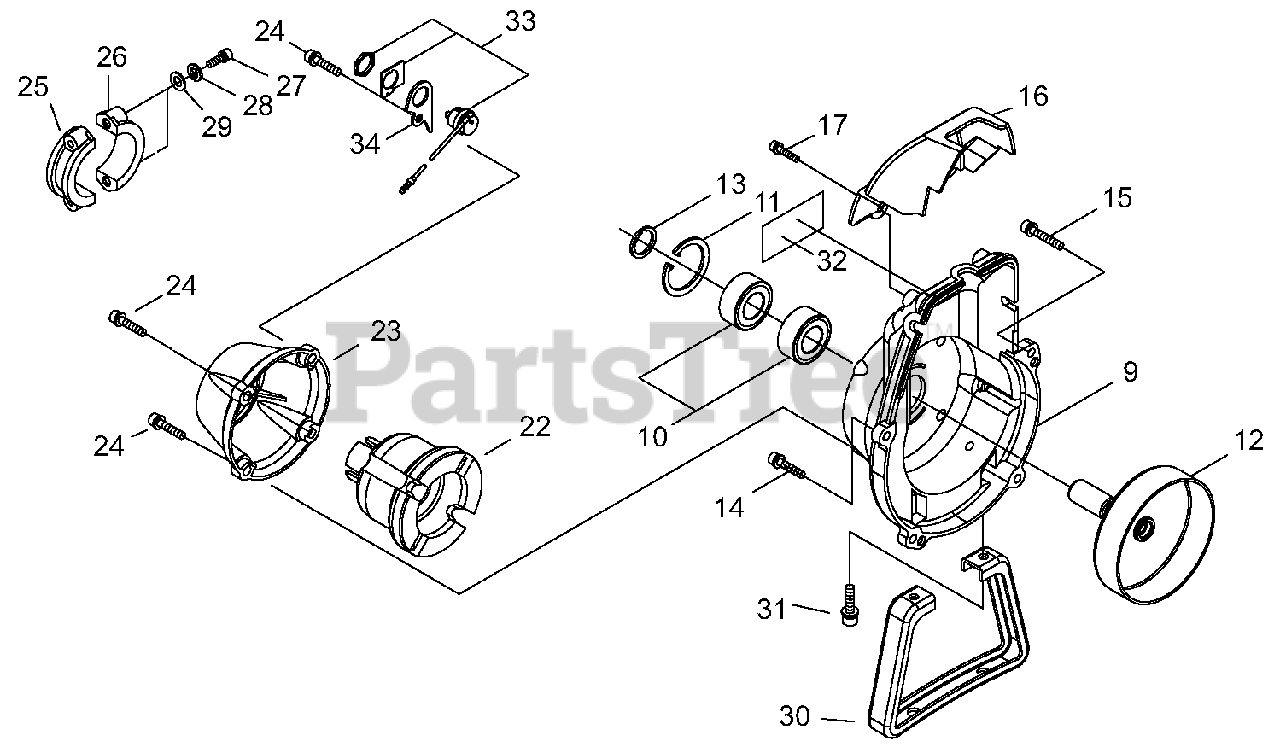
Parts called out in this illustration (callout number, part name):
9	CASE, FAN
10	BEARING, BALL - 6002
11	RING, RETAINING - 32
12	CLUTCH DRUM KIT
13	RING, RETAINING
14	SCREW - 5X20
15	SCREW - 5X30
16	PROTECTOR
17	SCREW - 4X16
22	CUSHION
23	CONNECTOR, CAP
24	SCREW - 5X20
25	CLAMP - A
26	CLAMP - B
27	SCREW - 5X25
28	LOCKWASHER - 5
29	WASHER - 5
30	GUARD, FUEL TANK
31	SCREW - 5X16
32	LABEL - MODEL B45LA
33	SWITCH, IGNITION
34	BRACKET, SWITCH
